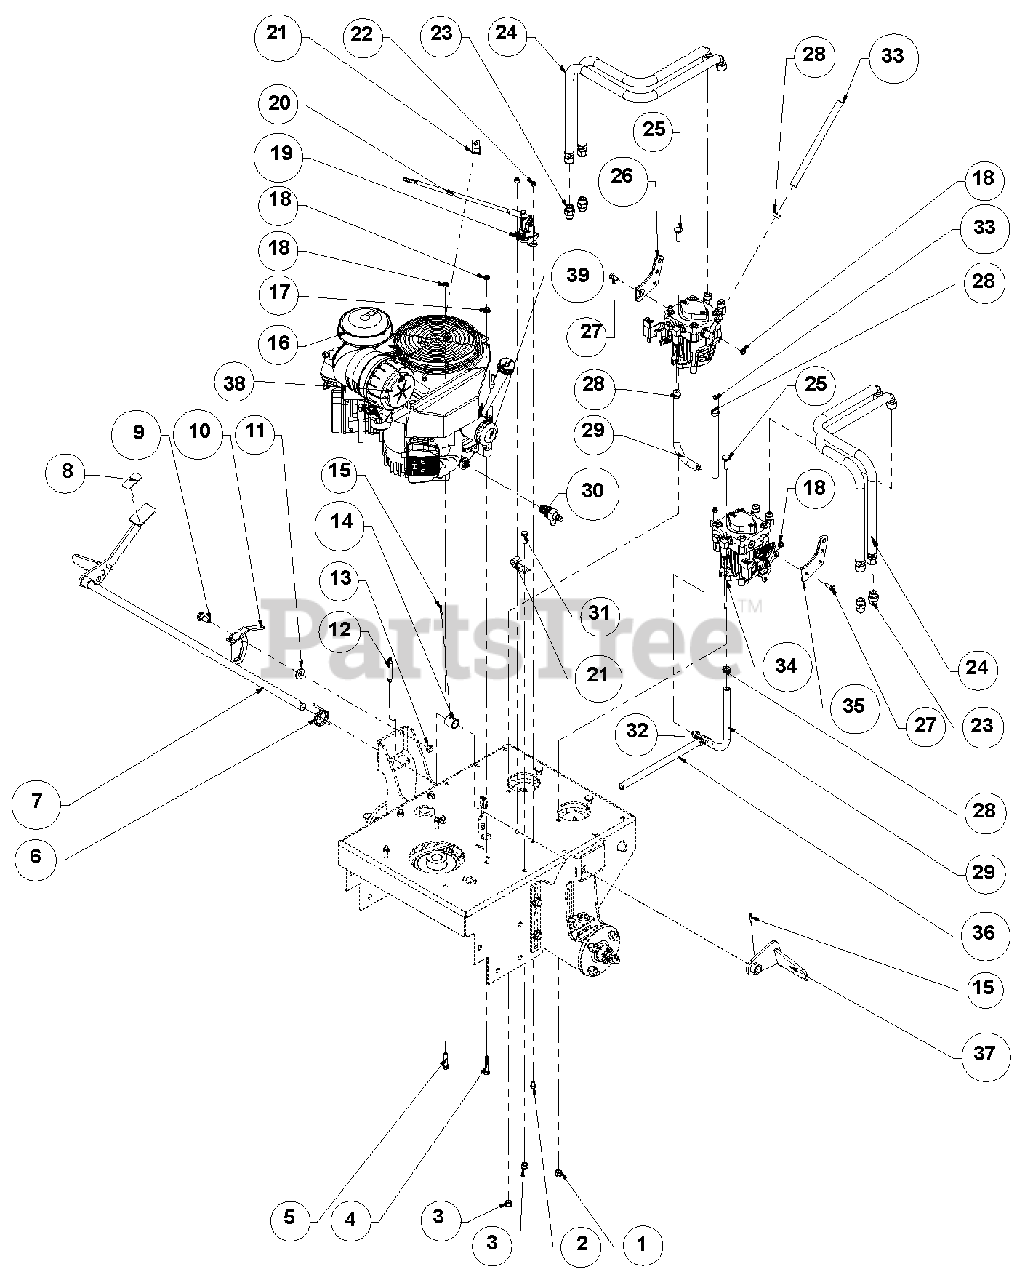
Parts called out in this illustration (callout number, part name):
1	Locknut, .38-16 Nyloc
2	Bolt, Hex .25-20 x .500 Grade 5
3	Locknut, .38-16 Nyloc
4	Bolt, .3125-18 x 1.75 Hex 5
5	Bolt, .3125-18 x 1.50 Hex 5
6	Spring, RH Torsion Parking Brake
7	Weldment Brake System, By Bracket (140, 141)
8	Tape, Traction- 1.00 x 2.00
9	Bolt, .50 x 1.06 x .38-16 SLD 5
10	Latch, Brake CBMB
11	Washer, .500 x 1.00 x .105 Flat
13	Locknut, .38-16 Center
14	Bushing, 1.00 x .188 x 1.00
15	Pin, Spring
16	Engine, Kawasaki 19HP FH580V (141, 142)
17	Locknut, .3125-18 WHIZ
18	Locknut, .3125-18 Nyloc
19	Solenoid
20	Cable, 12" Starter
21	Pillow-Clip, .500 Insulated
22	Locknut, .25-20 Nyloc
23	Fitting, Straight
24	Hose, Hydraulic .50 x 26 .50 EZFLEX
25	Bolt, Round Head Square Neck .38-16 x 1.25
26	Weldment, CSWS Hydro Pump Arm
27	Bolt, .3125-18 x .750 Hex 5
28	Clamp, Hose- .50 Pinch
29	Hose, Hydraulic .38 x 6.00
30	Fitting, Oil Drain
31	Bolt, .38-16 x 1.00 Hex 5
32	Fitting, TUN .38 Hose
33	Hose, Hydraulic .38 x 9.5
34	Assembly, Left Hand Pump Walkbehind
35	Weldment, CSWS Left Hand Hydro Pump Arm
36	Hose, Hydraulic .38 x 11.00
37	Weldment, Left Hand Brake Arm
38	Air Filter (141, 142)
39	Oil Filter
NS	Spark Plug
NS	Fuel Filter
